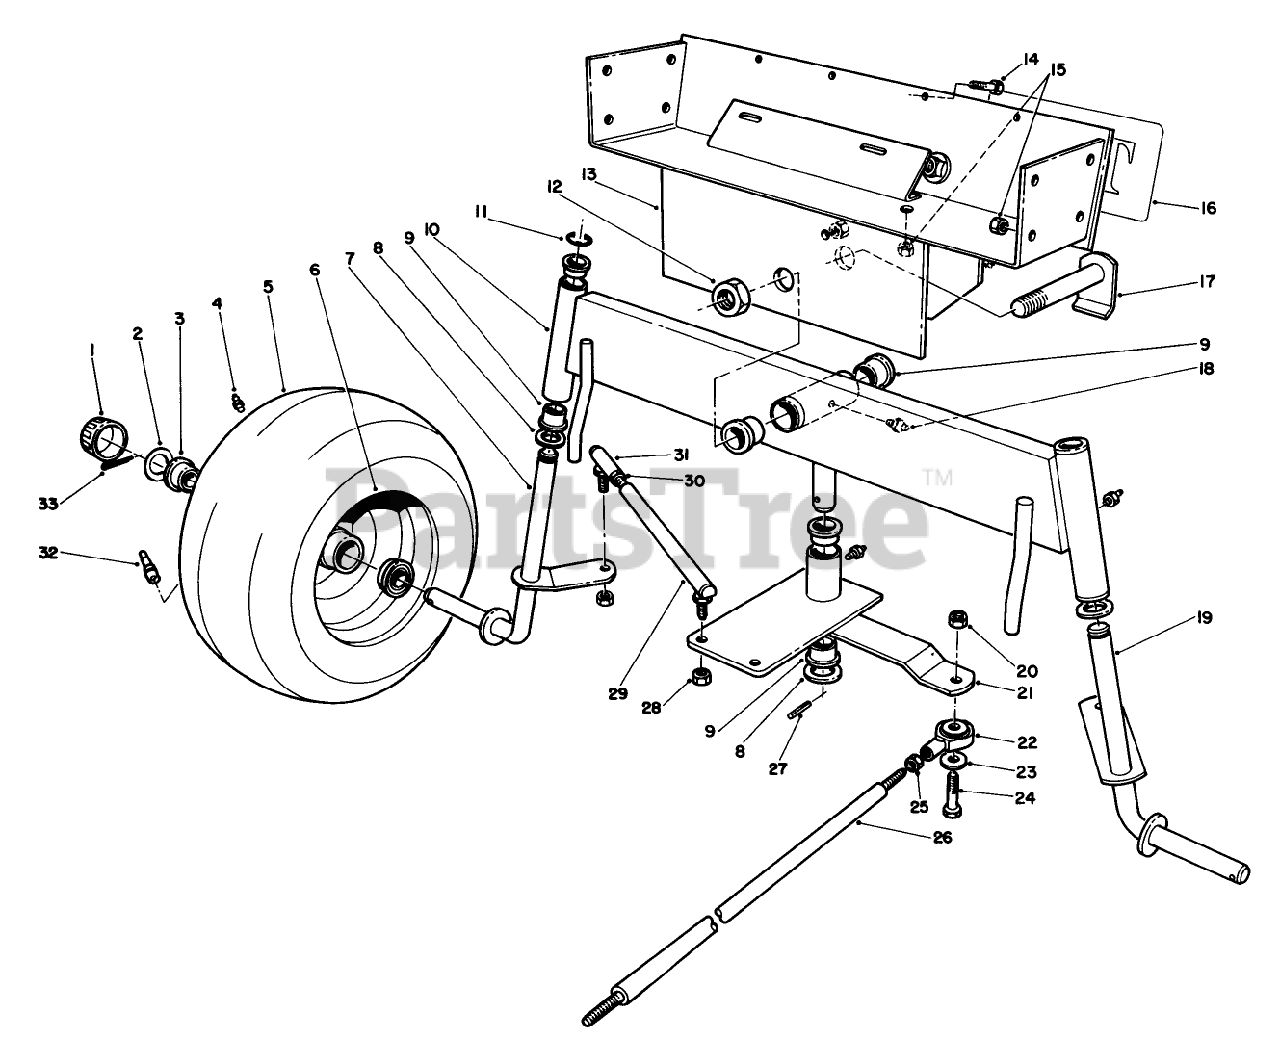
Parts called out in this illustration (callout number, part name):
2	WASHER-PLAIN
4	FITTING-GREASE
8	WASHER-THRUST
9	BEARING-FLANGE
11	E-RING
12	NUT-HEX
14	SCREW-HH
15	NUT-LOCK, NI
18	GREASE FITTING
20	NUT-HEX
22	BALL JOINT RH
23	WASHER-FLAT
24	SCREW-HH
25	NUT-JAM
27	PIN-SPRING
28	NUT-LOCK
29	STEERING TIE ROD
30	NUT-JAM
31	BALLJOINT-RH (W/GROMMET)
33	PIN-COTTER
